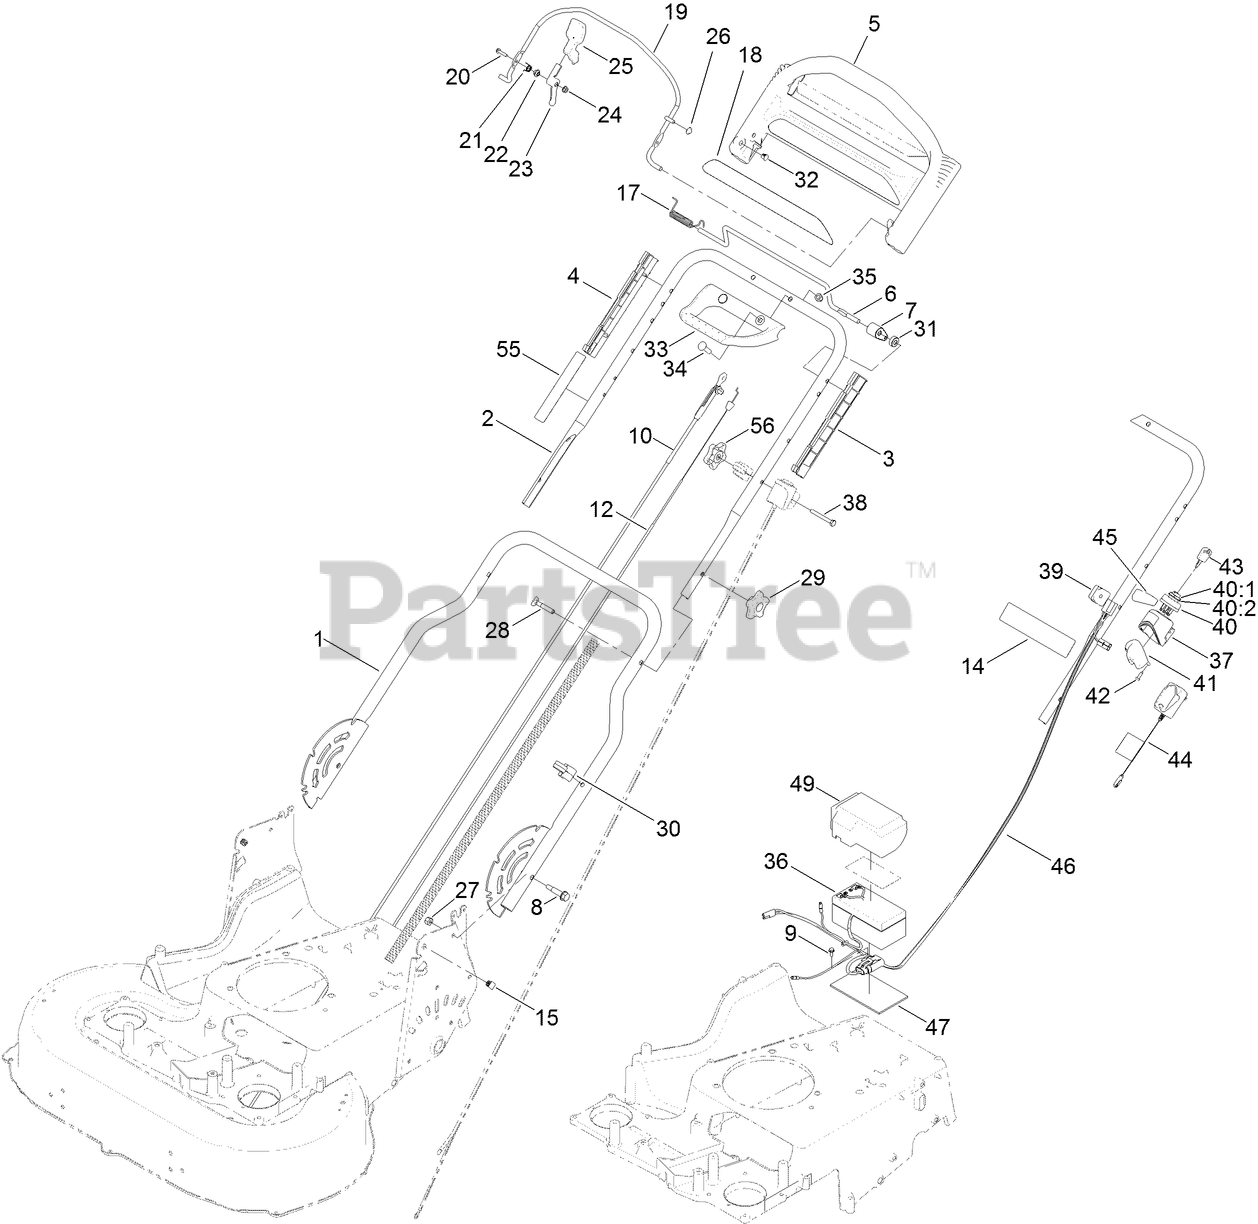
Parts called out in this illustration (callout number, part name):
1	HANDLE-LOWER
2	HANDLE-UPPER
3	GUIDE-LH
4	GUIDE-RH
5	HANDLE-CONTROL
7	LEVER-TRACTION
8	BOLT-SHOULDER, HHF
9	SCREW-TAPTITE
10	CABLE-BRAKE
12	CABLE-TRACTION
14	DECAL-WARNING
15	PLUG-SQUARE
18	DECAL-HANDLE
19	BAIL-BRAKE
20	SCREW-HWH
21	SPRING-TORSION
22	SPACER
23	LEVER
24	NUT-LOCK, FLANGE
26	NUT-SPEED
27	NUT-LOCK, NI
28	SCREW-HANDLE
29	KNOB-HANDLE
30	GUIDE-CABLE
31	SPACER
32	PLUG-DOME
33	HANDLE-ASSIST, TRACTION
34	BOLT-CARRIAGE
35	NUT-ACORN
36	BATTERY-WET
37	HOUSING-SWITCH, KEY
38	SCREW-HH
39	ANCHOR-CABLE, UPPER
40	SWITCH-STARTER
40:1	NUT-HH
40:2	WASHER-LOCK
41	COVER-SWTCH
42	SCREW-PPH
45	DECAL-SWITCH, IGNITION
46	HARNESS-WIRE
46:4	FUSE-40 AMP
47	FOAM-BATTERY
49	COVER-BATTERY
55	DECAL-TRACTION, ADJUST
56	KNOB-HANDLE, LOCKING
99	TIE-CABLE
